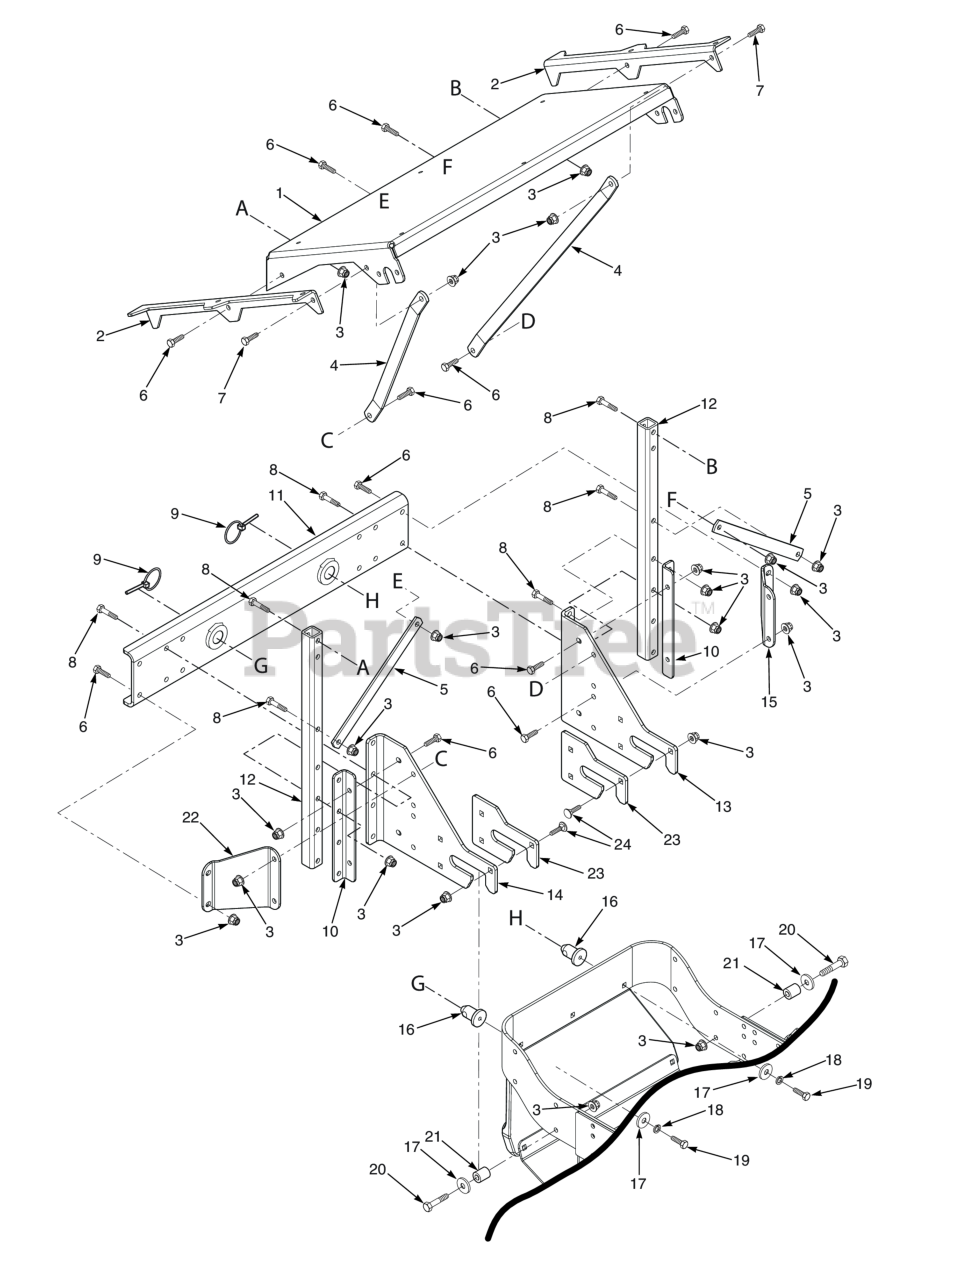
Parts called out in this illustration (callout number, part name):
1	Support Frame, Hopper
2	Bracket, Hopper Support
3	Nut, Flange Elastic Stop Nut, 3/8-16
4	Brace, Stiffener
5	Brace, Engine Mounting
6	Bolt, Hex Head, 3/8-16 x 1 Gr. 5
7	Bolt, Hex Head 3/8-16 x 1-1/4" Grade 8
8	Bolt, Hex Head 3/8-16 x 2-1/4" - 61"
9	Quick Pin, 5/16" Dia.
10	Mounting Bracket, Tube
11	Mounting Bracket Weldment
12	Tube, Upright
13	Mounting Bracket, GC R.H.
14	Mounting Bracket, GC L.H.
15	Angle Bracket, GC
16	Pin, GC Locator
17	Flatwasher, 3/8-.406 x 1-1-1/2 x 7 Gauge
18	Lockwasher, 3/8" Spring, Kawasaki FX / FT & FT-EFI / B&S 32BV
19	Bolt, Hex Head 3/8-16 x 1-1/4" Grade 8
20	Bolt, Hex Head 3/8-16 x 2-1/4" - 61"
21	Spacer
22	Angle Bracket, GC
23	Wear Plate, GC
24	Carriage Bolt, 3/8-16 x 1-1/4"
